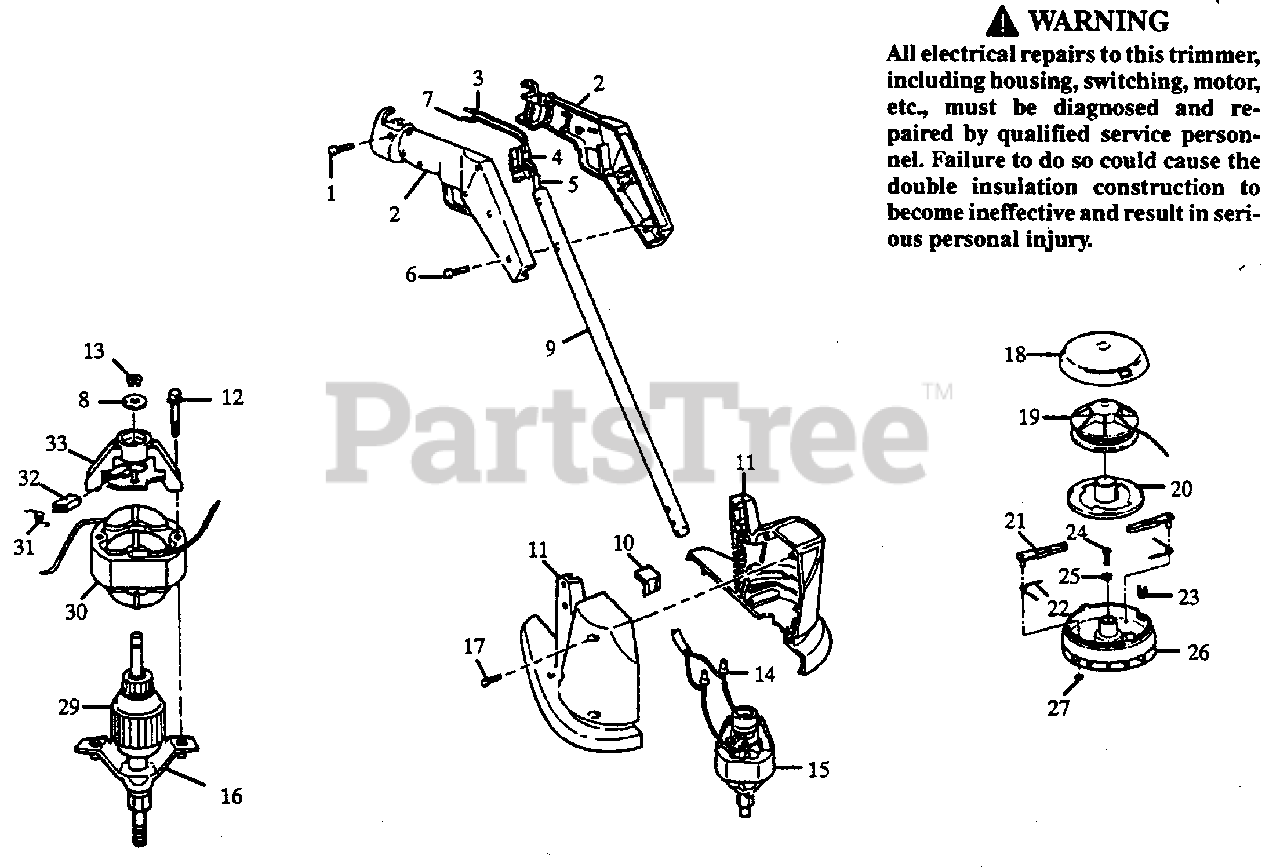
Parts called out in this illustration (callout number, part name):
2	Handle Set
4	Trigger Switch
8	Washer,Shim
10	Line Cutter
11	Housing Set
13	Retaining Ring
14	Terminal Cap
15	Motor/Adapter Ass'y.
16	End Bell
19	Spool w/Line
23	Line Shield
26	Housing Ass'y. (Inc. 21-23,26,27)
27	Push Nut
29	Armature/Endbell Ass'y.
30	Field Ass'y.
31	Brush Spring
32	Carbon Brush
33	Bracket/Plate Ass'y.
